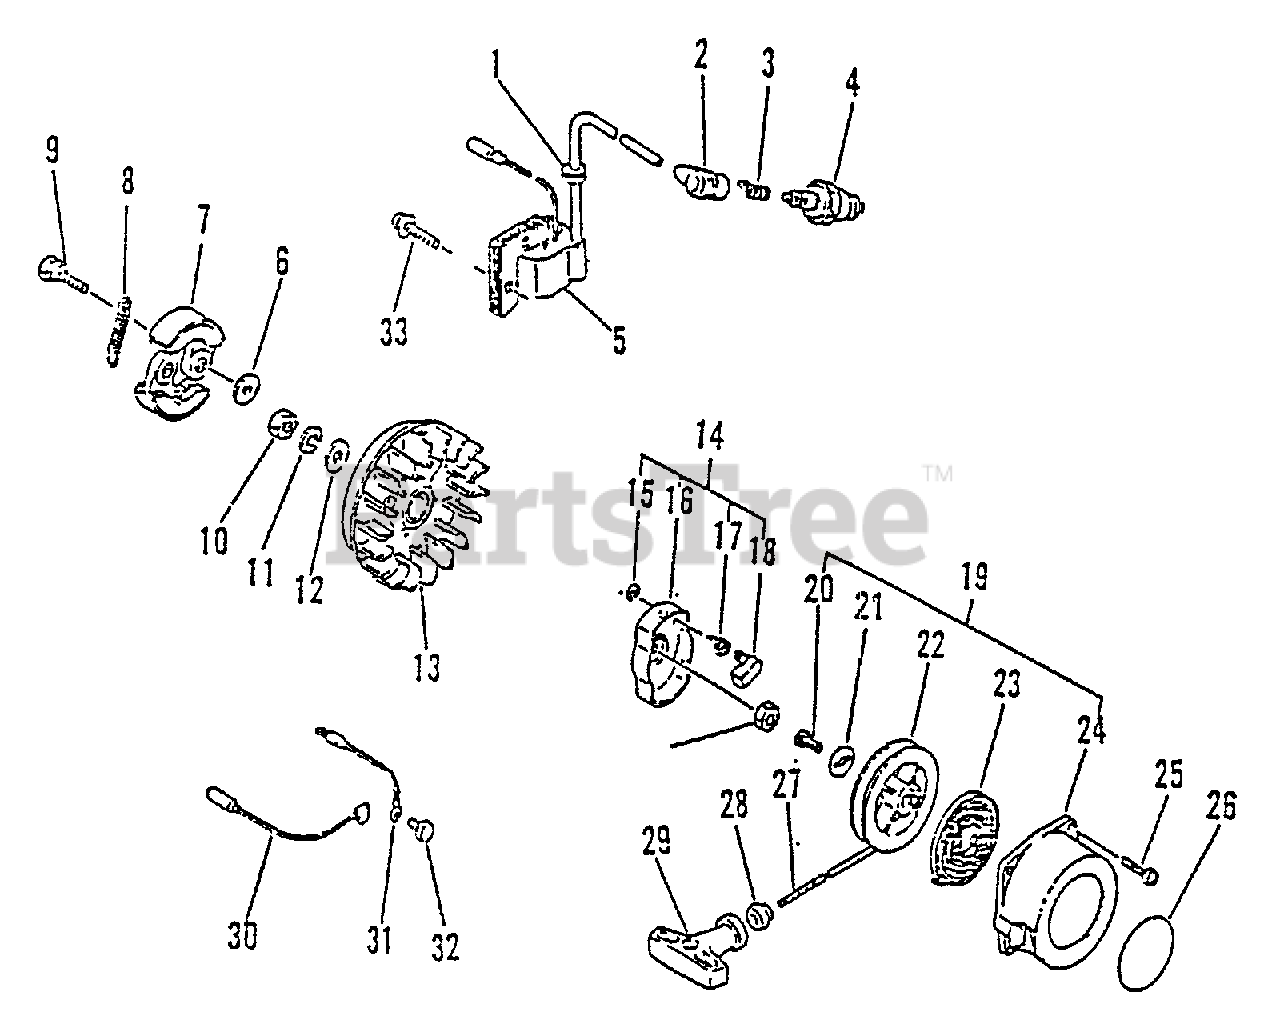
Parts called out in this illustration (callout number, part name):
2	CAP, SPARK PLUG
3	TERMINAL, SPARK PLUG
4	SPARK PLUG - BPM7A
5	COIL, IGNITION
6	WASHER 6.2×19×1.0
7	SHOE, CLUTCH
8	SPRING, CLUTCH
9	BOLT, CLUTCH
10	NUT 8×1.25
11	WASHER, SPRING 8
12	WASHER 8.5×16×1.2
13	FLYWHEEL
14	PAWL ASSY, STARTER
15	E-RING 4
16	CATCHER, PAWL
17	SPRING, RETURN
18	PAWL, STARTER
19	STARTER ASSY
21	WASHER
22	REEL, ROPE
23	SPRING, RECOIL
24	CASE, STARTER
25	BOLT 4×14
26	LABEL, ECHO
27	ROPE, STARTER 3.5×850
28	GUIDE, ROPE
29	GRIP, STARTER
30	LEAD - GROUND
31	LEAD - GROUND L= 115
32	SCREW 5×10
33	BOLT 5×25
